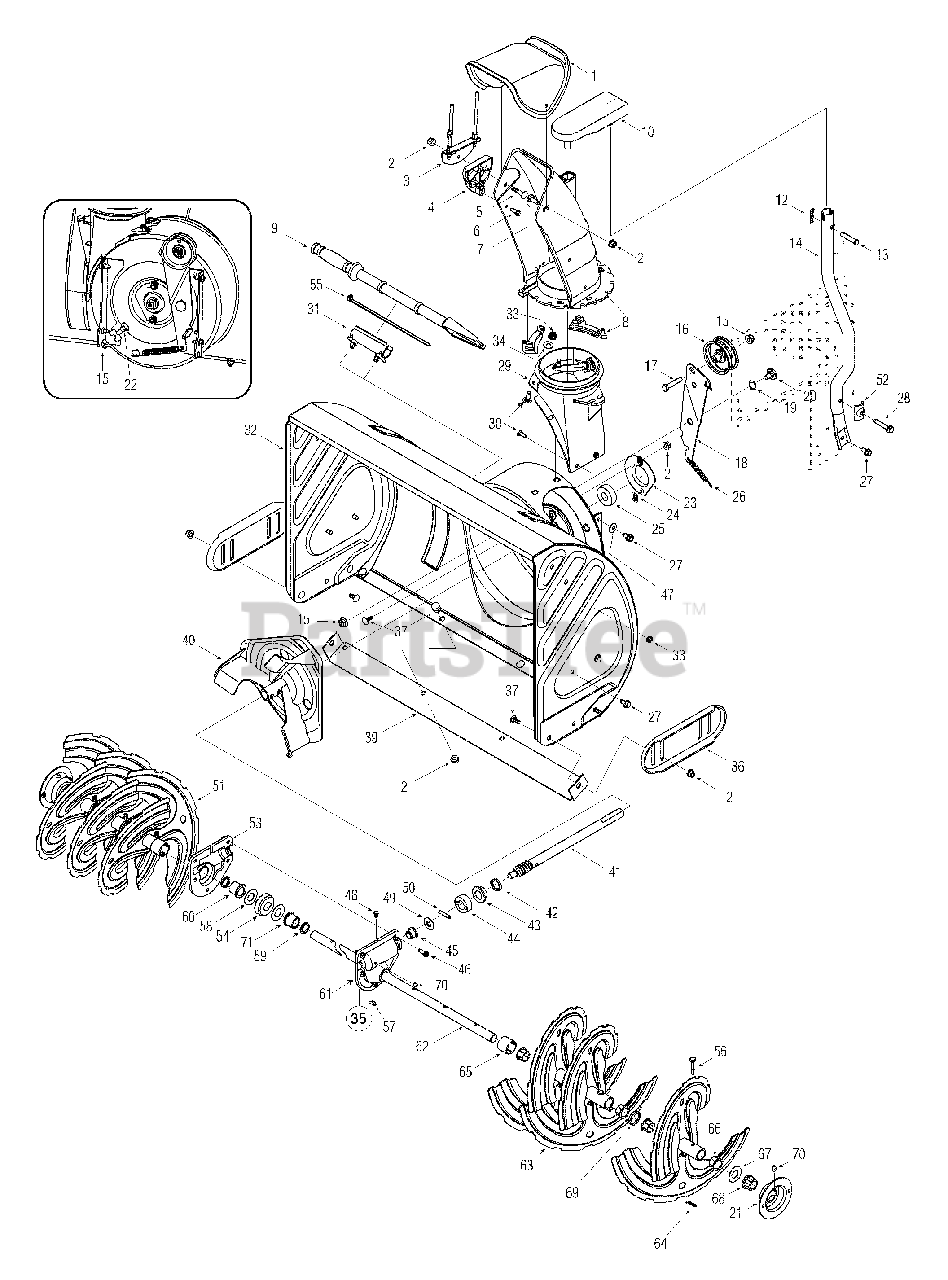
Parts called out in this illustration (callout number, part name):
1	Upper Chute
2	Flange Lock Nut, 5/16-18
4	Chute Tilt Cable Guide
5	Carriage Bolt, 5/16-18 x 1.50
6	Hi-Lo S crew, 1/4-15x 0.75
7	Carriage Bolt, 5/16-18 x 1.0
8	Lower Chute Assembly
9	Clean-Out Tool
10	Kit, Chute Control Assembly
12	Cotter Pin
13	Clevis Pin
16	Flat Idler Pulley
17	Hex Bolt, 3/8-16 x 1.75
19	Wave Washer
20	Shoulder Screw
22	Shoulder Screw
23	Bearing Housing
25	Ball Bearing
26	Extension Spring
27	AB Screw, 5/16-12 x 0.75
28	TT Screw, 5/16-18 x 1.750
29	Chute Adapter
30	Carriage Screw, 1/4-20 x 0.75
31	Clean-out Tool M tg. Bracket
33	Flange Lock Nut, 1/4-20
34	Flat Washer
35	Gearbox Assembly Complete
37	Carriage Bolt
41	Worm Shaft
43	Flange Bearing
44	Thrust Collar
45	Flange Bearing
46	TT Screw, 1/4-20 x 0.75
47	Bell Washer
49	Flat Washer
52	Handle Tab
53	Reducer Hsg.-RH
54	Worm Gear, 20T
55	Cable Tie
56	Shear Pin
57	Key
58	Flat Washer
60	Flange Bearing
61	Reducer Hsg.-L H
62	Auger Axle
64	Bow Tie Cotter Pin
65	Spacer, 1.25OD x.75ID x 1.00 Lg
66	Flange Bushing
67	Flat Washer
68	Hex Flange Bearing
69	Spacer, 1.25OD x.75ID x 3/16 Lg
70	Lube Fitting
71	Flange Bearing
